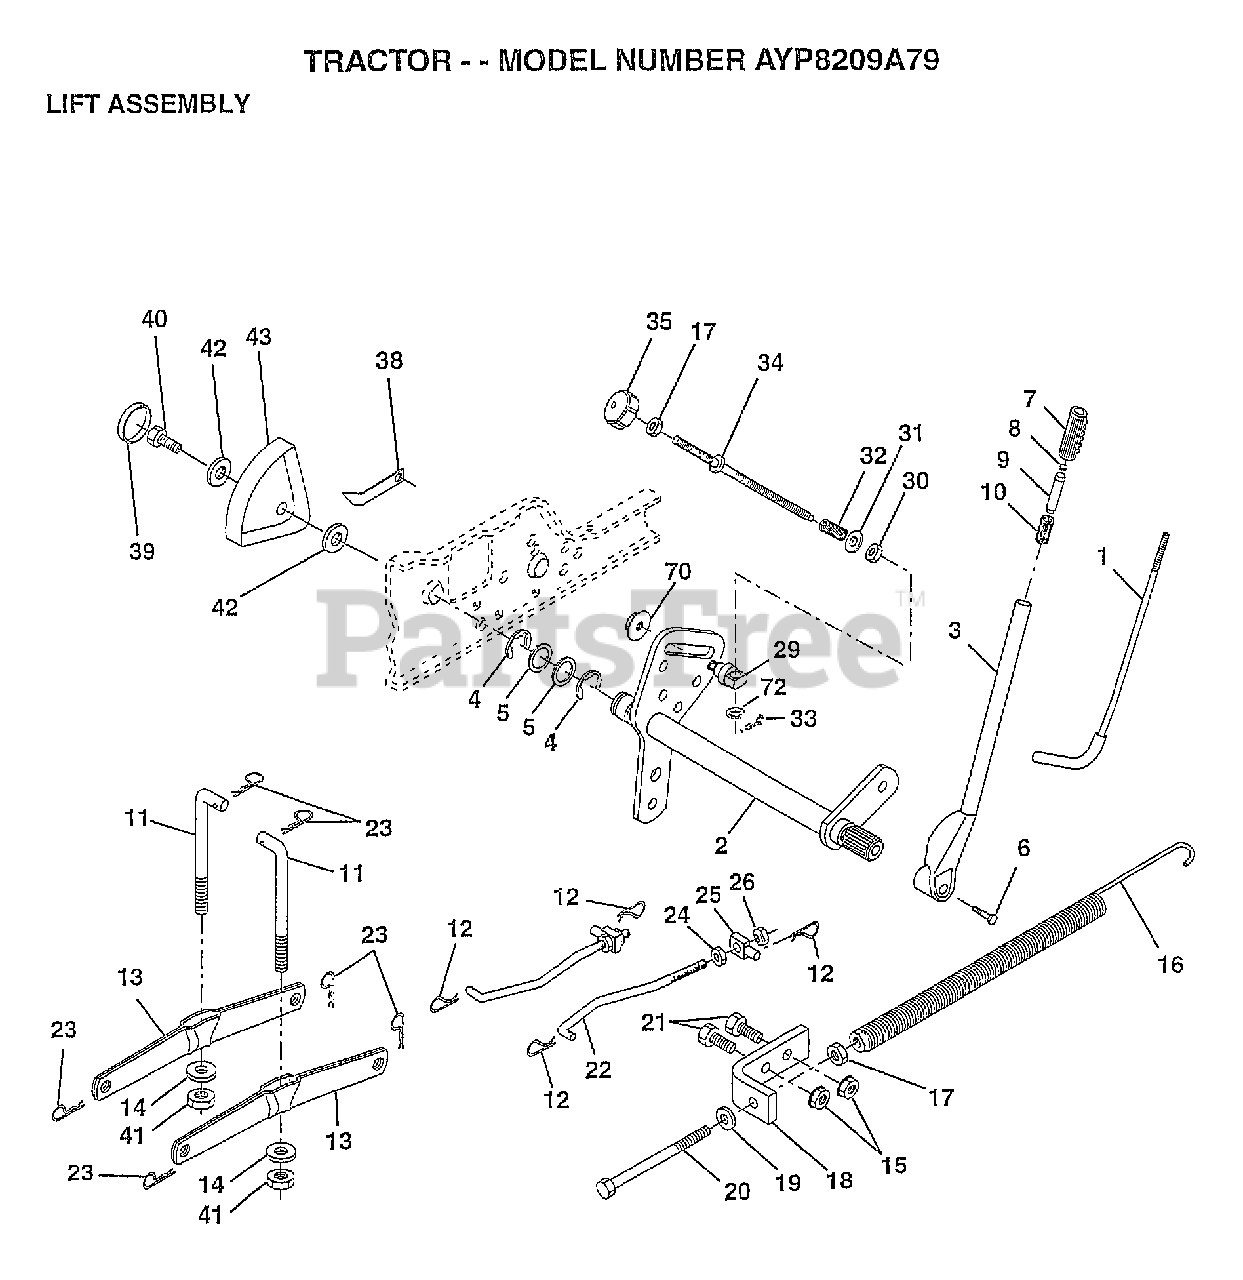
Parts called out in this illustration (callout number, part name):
1	LEVER ROD LT
2	SHAFT AMS LIFT
4	E-RING
5	WASHER
6	"BOLT,HEX"
7	GRIP HANDLE
10	SPRING T
11	LINK.LIFT.MWR.VGT
12	RETAINER.SPRING
13	ARM SUSP REAR
14	BEARING PVT LH
17	NUT
18	BRACKET SPRING AS
19	WASHER
20	BOLT-ADJ SPRING T
21	BOLT
22	LINK.FRONT
24	NUT
25	TRUNION
26	NUT.LK.W/WSH.1/2.
29	TRUNNION
30	NUT T
31	WASHER
32	SPRING.COMP.INF.H
34	ROD.ADJ.LIFT
35	KNOB INF 3/8-16
38	POINTER-INDICAT
39	"PLUG,HOLE"
40	SCREW
41	NUT.CROWNLOCK.3/8
42	WASHER
43	HEIGHT INDICATOR
70	NUT.HXFLG.LOCK.
72	NUT PUSH M
